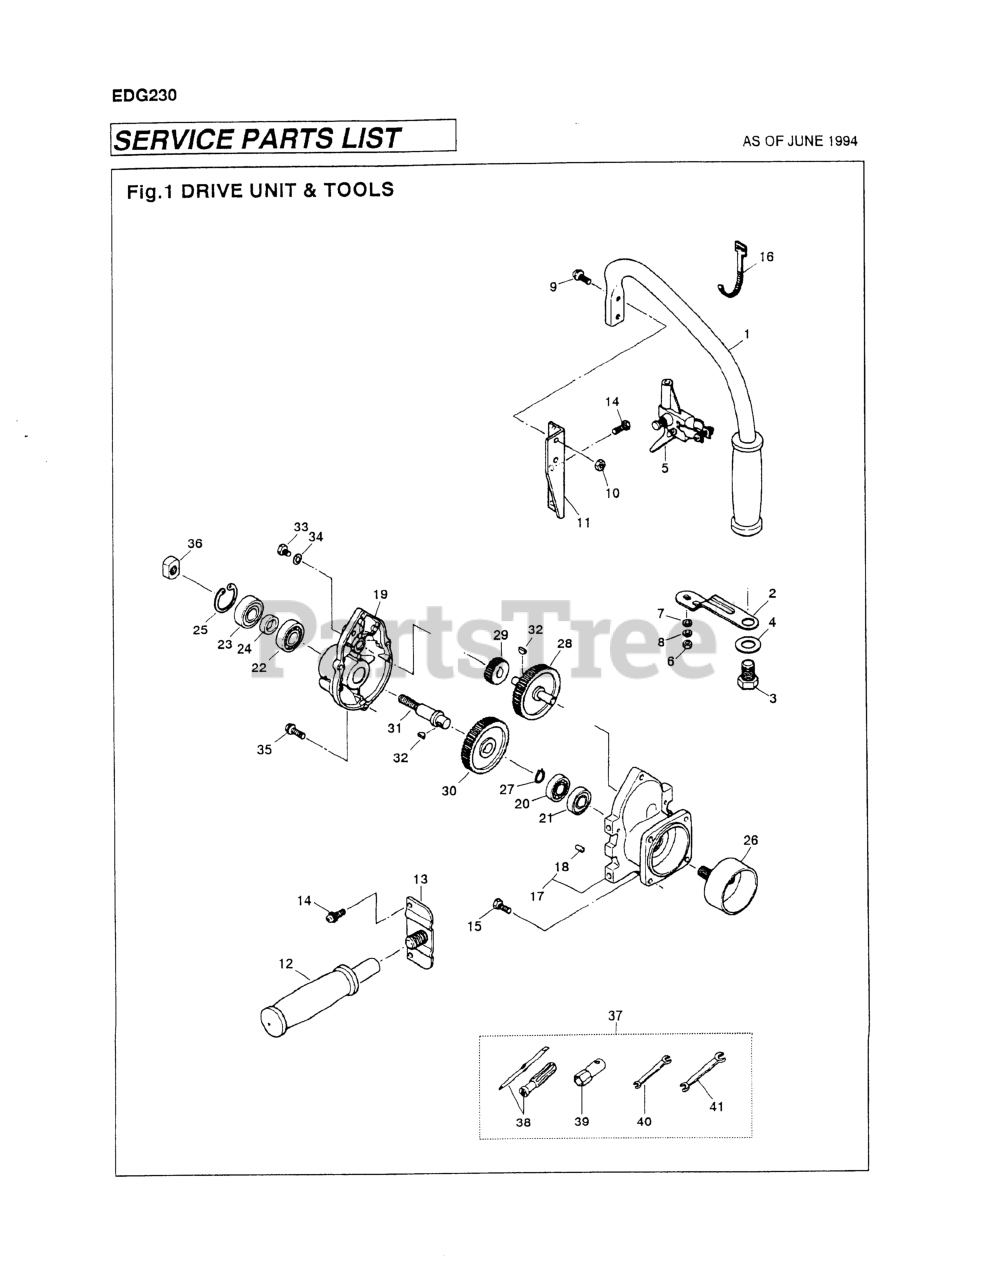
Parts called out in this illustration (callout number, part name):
1	HANDLE, RIGHT
2	STAY
4	WASHER, M14 x 2.3
5	LEVER, THROTTLE
6	NUT, M5 X 4
7	WASHER, SPRING M4 x 1.3
8	WASHER, M5 X .8
9	SCREW, M5 x 16
10	NUT, M5 X 4
11	BRACKET, RIGHT
12	HANDLE, LEFT COMP
13	BRACKET, LEFT
14	BOLT, M6 x 16
15	BOLT, M6 x 16
16	BAND
18	PIN, DOWEL
19	CASE (USE -11201)
20	BEARING
25	RING, SNAP, M35 X 1.5
26	DRUM, CLUTCH
27	RING, SNAP (RPLS 3130-13270)
28	GEAR, DRIVE(USE 13101)
29	GEAR, IDLER
30	GEAR, DRIVEN
31	SHAFT, PTO
32	KEY
33	BOLT, M6 x 10
34	WASHER, M6 X .8
35	BOLT M5 x 20 (RPLS -12280)
37	TOOL SET
38	SCREWDRIVER
39	SOCKET, HEX, 3/4
40	SPANNER, 8 X 10 (RPLS 2540- )
41	WRENCH (TOOL)
